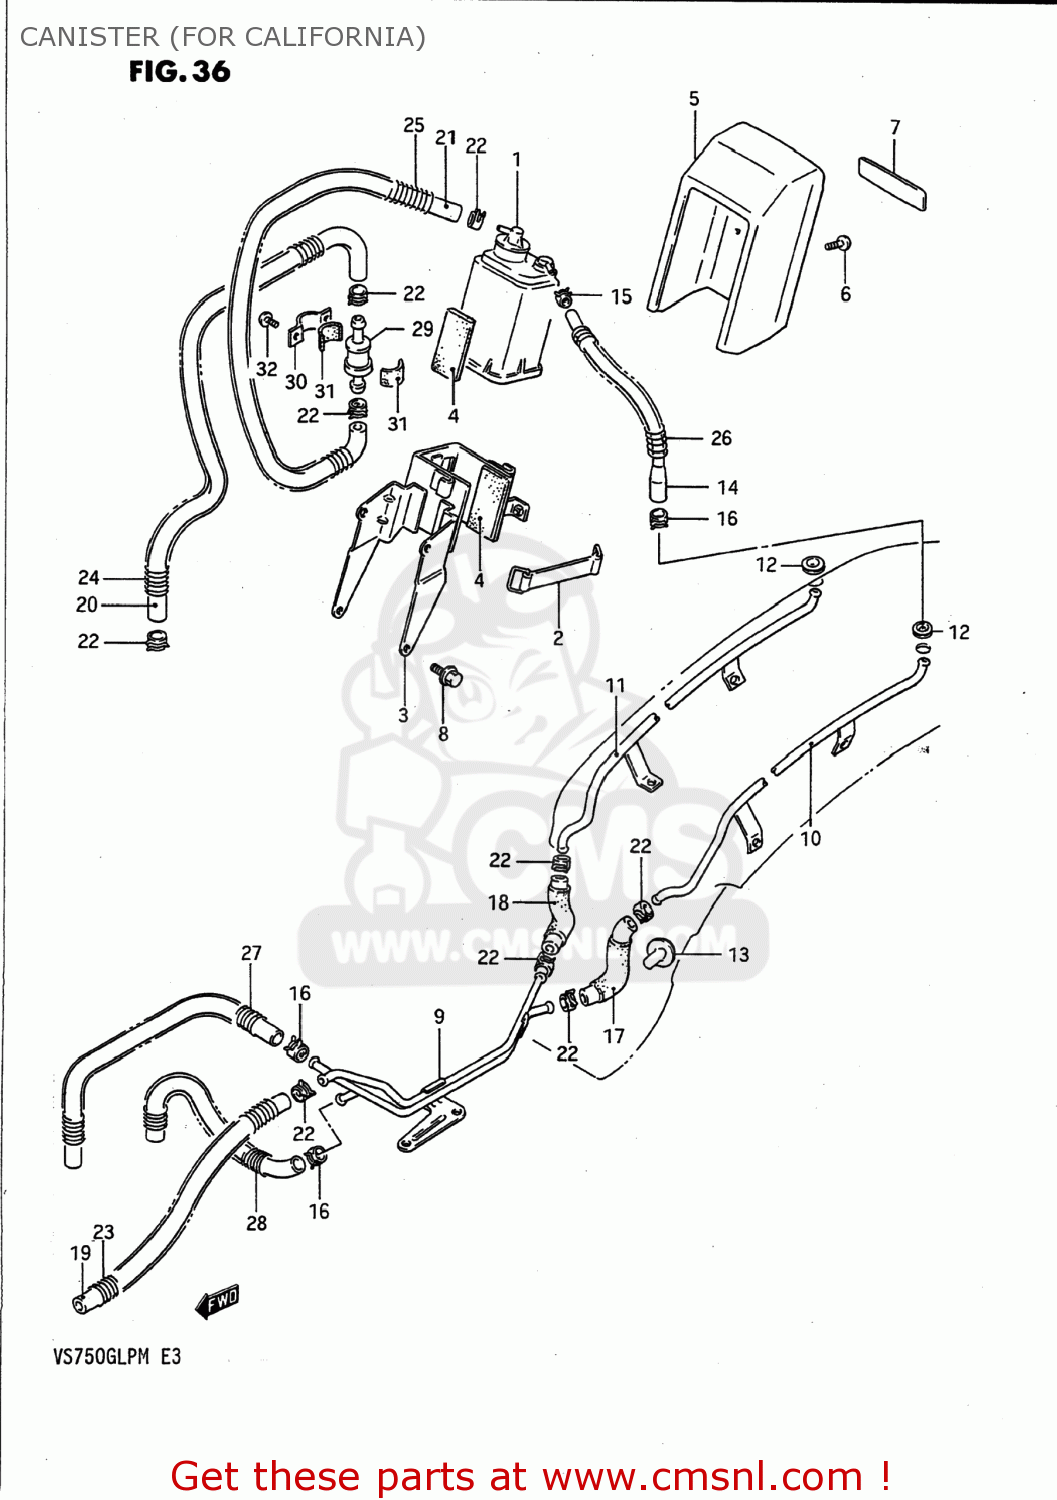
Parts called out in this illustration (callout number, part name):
1	CANISTER ASSY,CHARCOAL
2	BAND
3	BRACKET,CANISTER
4	CUSHION
5	COVER,CANISTER
6	SCREW (5X10)
7	EMBLEM
8	BOLT
9	PIPE,CSTR JOINT FR
10	(CA) PIPE,CANISTER JOINT REAR
11	(CA) PIPE,CANISTER JOINT REAR
12	GROMMET
13	GROMMET
14	HOSE,PURGE NO.1
15	CLAMP
16	CLIP
17	(CA) HOSE NO.6
18	(CA) HOSE NO.2
19	HOSE(5.4X11.4X2000)
20	HOSE
21	HOSE
22	(CA) CLIP
23	SPRING
24	(CA) SPRING
25	SPRING
26	SPRING
27	SPRING
28	SPRING
29	VALVE,FUEL TANK BREATHER
30	PLATE,FUEL TANK BREATHER NO.2
31	CUSHION
32	SCREW
